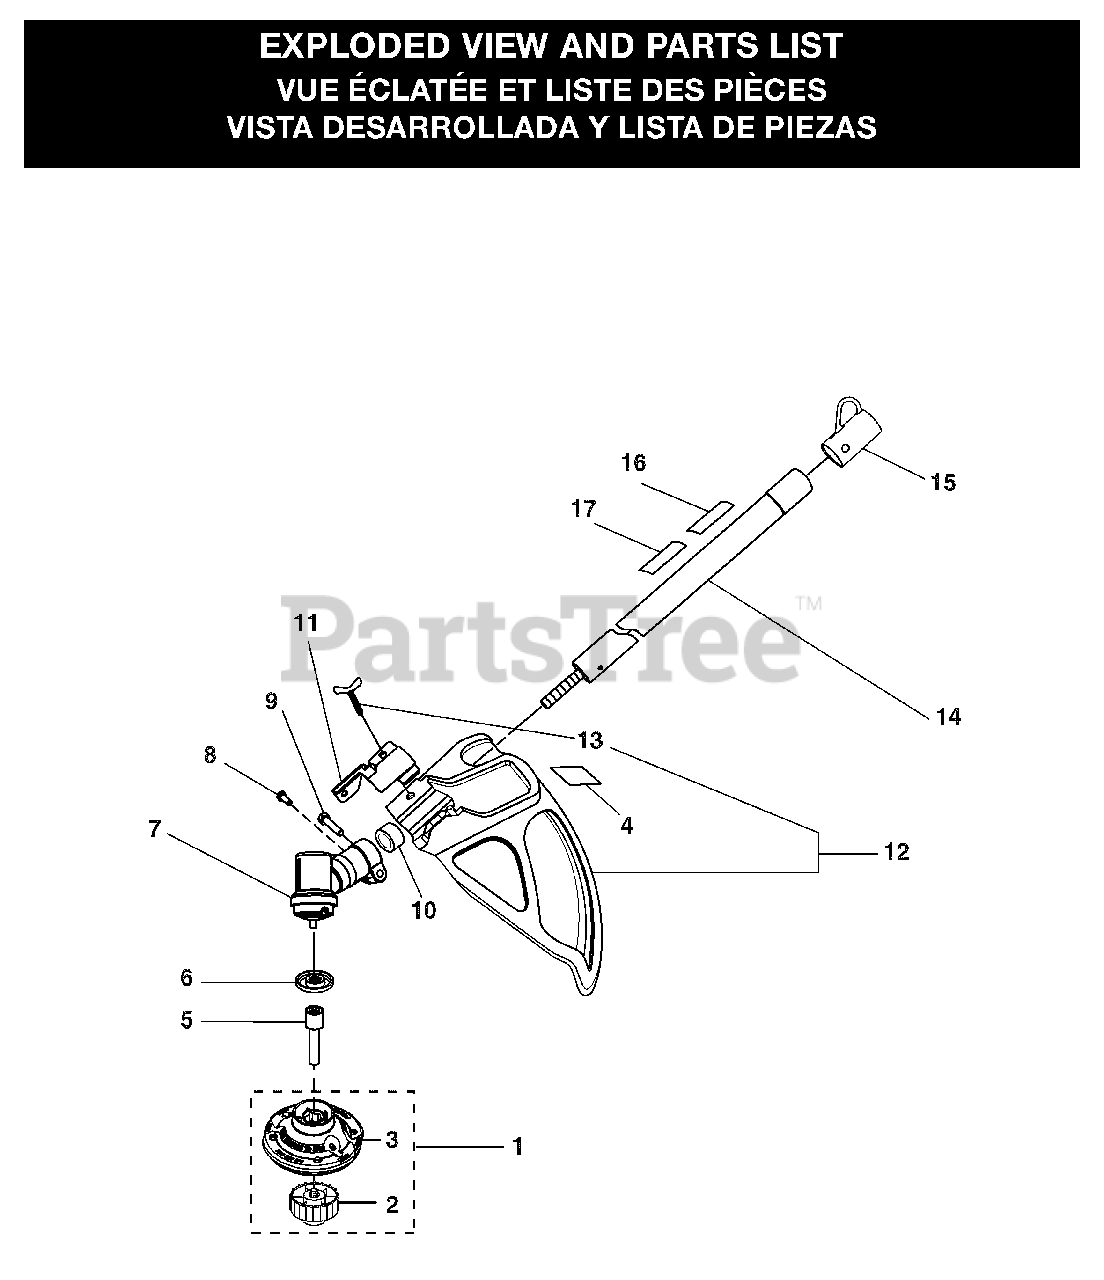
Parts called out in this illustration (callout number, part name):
1	Pro Cut II String Head Assembly
2	Spool Retainer Assembly
3	Pro Cut II String Head
4	Logo Label
5	String Head Adapter
6	Flanged Washer
7	Gear Case Assembly
8	Screw (#10-24 x 5/8 in., Hex Washer Hd.)
9	Screw (1/4-20 x 1-1/4 in.)
11	Clamp
12	Grass Deflector Assembly
13	Winged Head Screw (1/4-20 x 3/4-in.)
14	Boom Assembly
15	Hanger Cap
16	Warning Label
17	Logo Label
